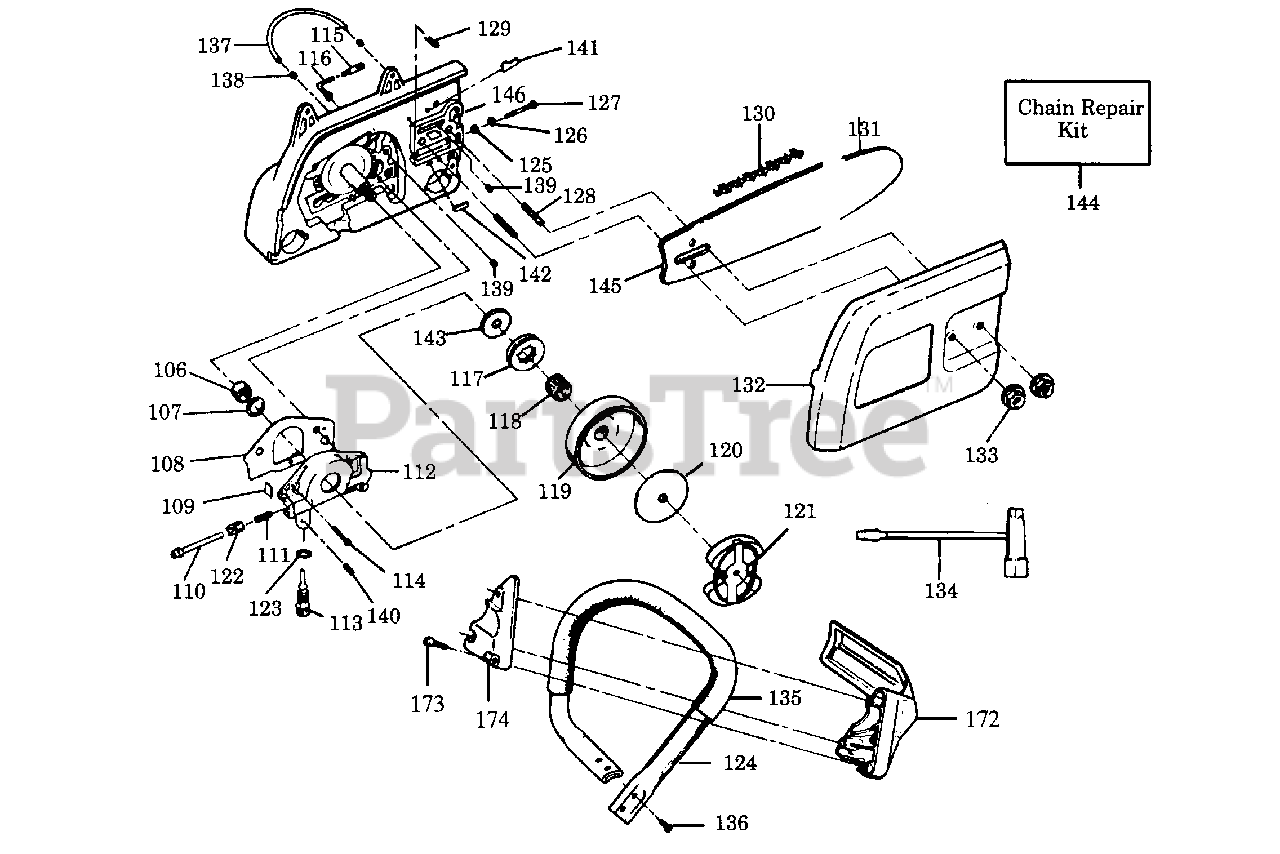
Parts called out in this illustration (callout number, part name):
106	Worm Gear
108	Gasket Set
109	Dust Plug
112	Oil Pump Kit
114	Screw
115	Oil Pickup & Filter
116	Oiler Intake Line
117	Rim Sprocket (3000 only)
119	Drum Sprocket (Model 2700,2800,3300)
119	Drum (Model 3000)
120	Clutch Plate
121	Clutch Ass'y.
122	Oiler Gear Spur
123	"O" Ring
124	Handlebar Ass'y.
125	Bar Adjusting Pin
126	"E" Ring
127	Screw
128	Bar Stud
129	Vent Pin
130	Chain 16"
130	Chain 18"
130	Chain 20"
131	Replaceable Sprocket Nose
132	Bar Clamp Ass'y.
133	Nut
134	Scrench
137	Oiler Discharge Line
138	Oiler Discharge Sleeve
139	Tubing Nut
140	Oiler Adjustment Pin
141	Chain Pad - Top
142	Chain Pad
143	Thrust Washer
144	Chain Repair Kit
145	Model 2800
145	Model 3000,3300
145	Model 3000
145	Model 2700,3100,3300
146	Crankcase Plug
172	Handguard - See also 65 External Power Unit
174	Handguard Cap
